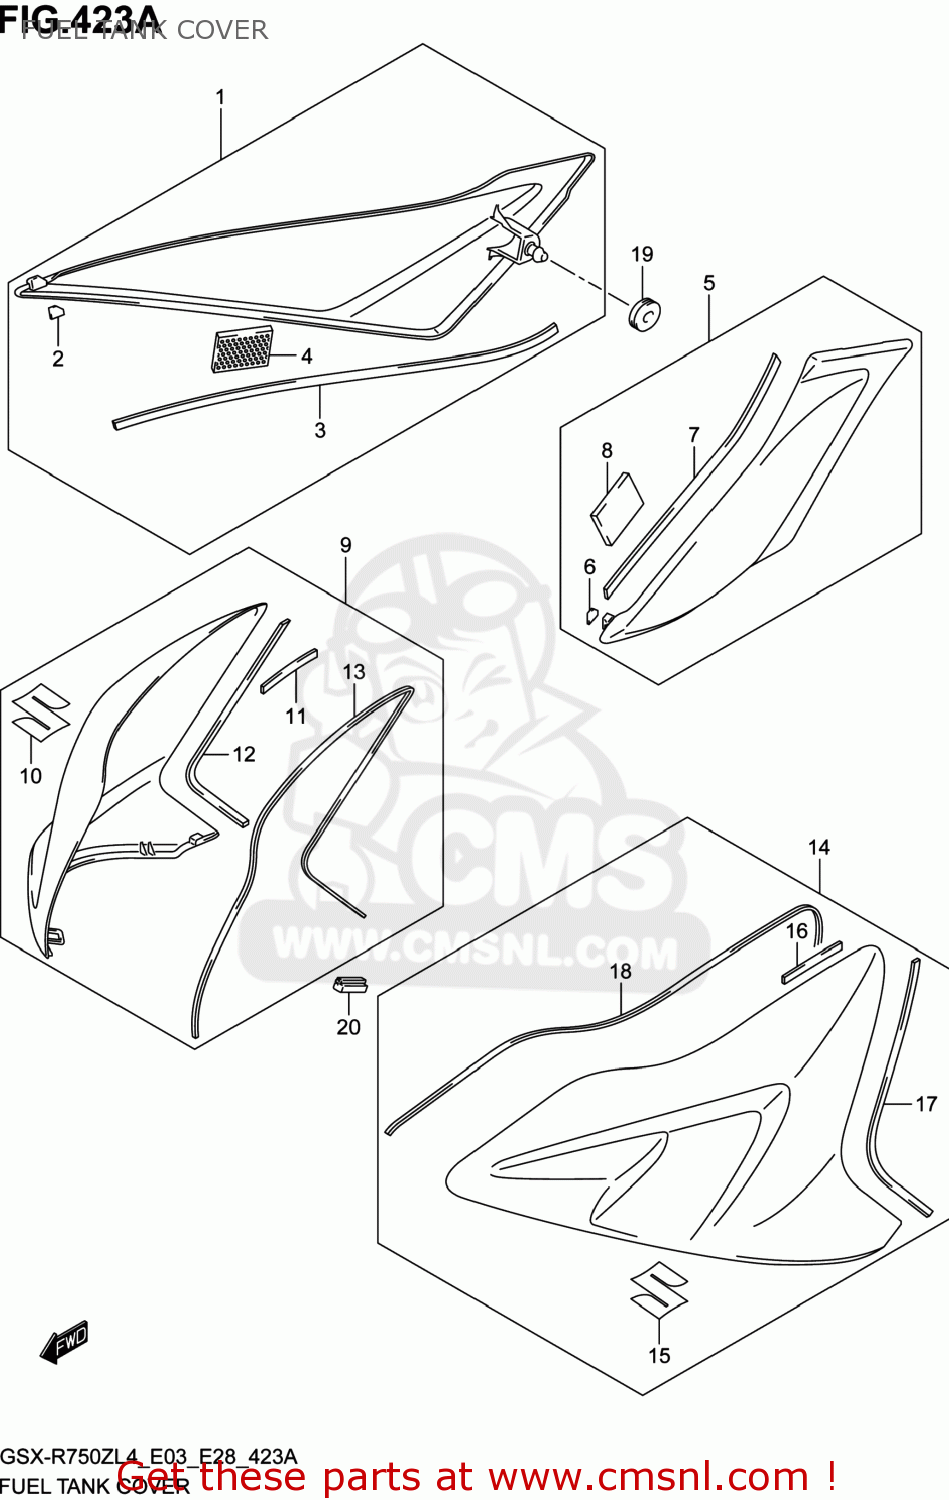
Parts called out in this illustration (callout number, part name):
1	COVER,FUEL TANK SIDE,R
2	CUSHION,FUEL TANK COVER
3	CUSHION,FUEL TANK SIDE COVER
4	FASTENER
5	COVER,FUEL TANK SIDE,L
6	CUSHION,FUEL TANK COVER
7	CUSHION,FUEL TANK SIDE COVER
8	FASTENER
9	COVER,FUEL TANK FRONT,R(RED)
10	EMBLEM, S
11	CUSHION,FUEL TANK COVER NO.1
12	CUSHION,FUEL TANK COVER,R NO.2
13	CUSHION,FUEL TANK COVER FR
14	COVER,FUEL TANK FRONT,L(RED)
15	EMBLEM, S
16	CUSHION,FUEL TANK COVER NO.1
17	CUSHION,FUEL TANK COVER,L NO.2
18	CUSHION,FUEL TANK COVER FR
19	CUSHION,FUEL TANK COVER SIDE
20	CUSHION,FUEL TANK COVER FR
